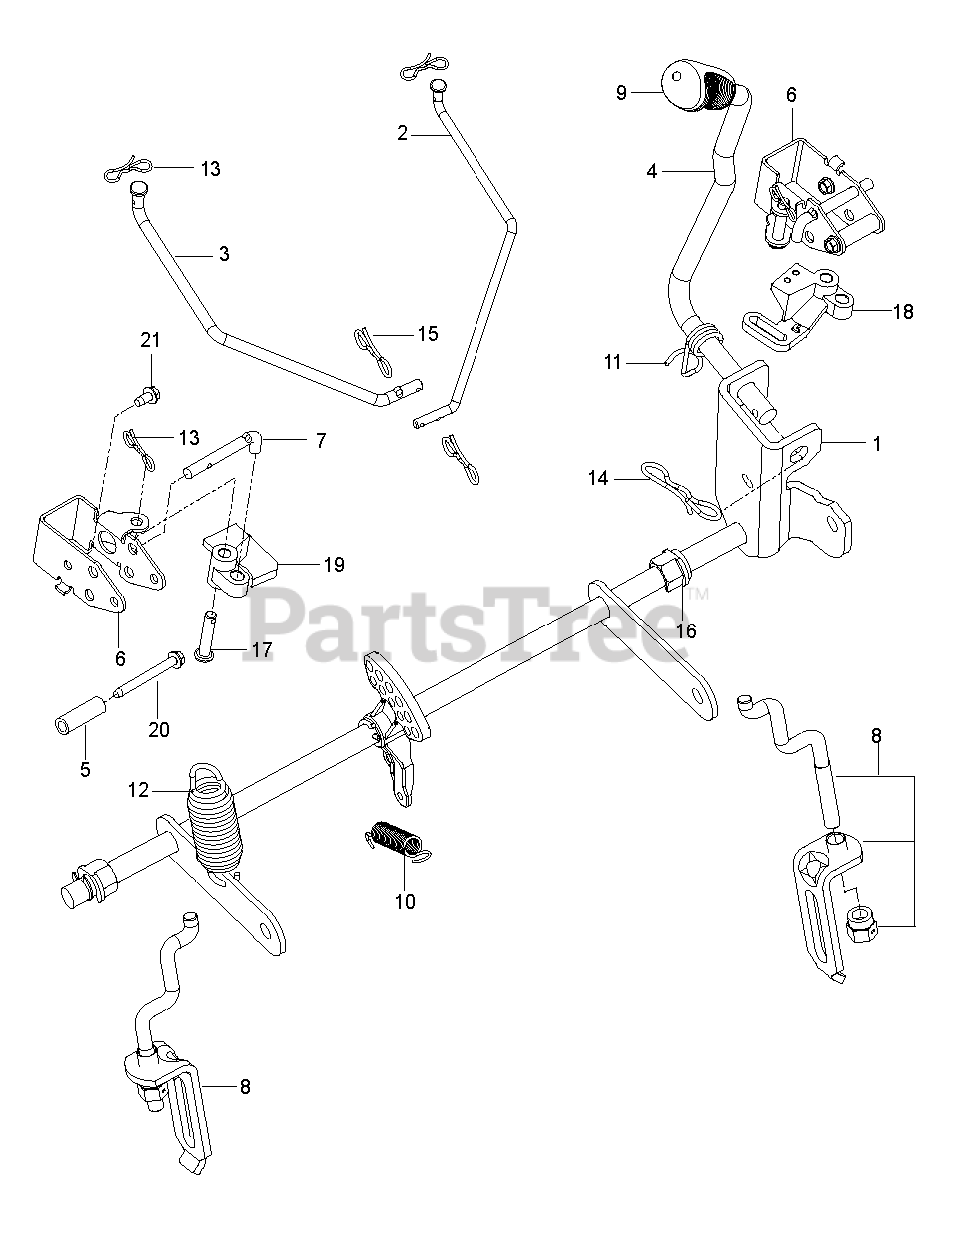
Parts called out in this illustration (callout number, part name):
1	SHAFT.ASM.RZ.DECK.LIFT.SRV
2	LINK.BRAKE.PARK.UPPER.LH
3	LINK.BRAKE.PARK.UPPER.RH
4	LIFT.LEVER.ASM.RZ.SERVICE
5	SPACER.334.ID.5.OD.1.5.L
6	BRACKET.BELLCRANK.PBRAKE X431
7	LINK.ASM.RZ.LIFT.SERVICE
8	GRIP.HANDLE.LIFT.PVC.428
9	RETURN.BRAKE.PARK.AUTO
10	SPRING.TORSION.LIFT.HANDLE
12	PIN COTTER;LOCKING;BOWTIE;1IN
13	PIN.COTTER.7/16.BOW TI.
14	PIN.COTTER.5/16.BOW TI
15	PLASTIC NUT
16	PIN.5.16X1.5
17	BELLCRANK.RH
18	BELLCRANK.LH
19	ROD.PUSH.BRAKE
20	SCREW.1/4-20X5/8
21	SCREW THD;ROLL;1/4-20 X 2.25
